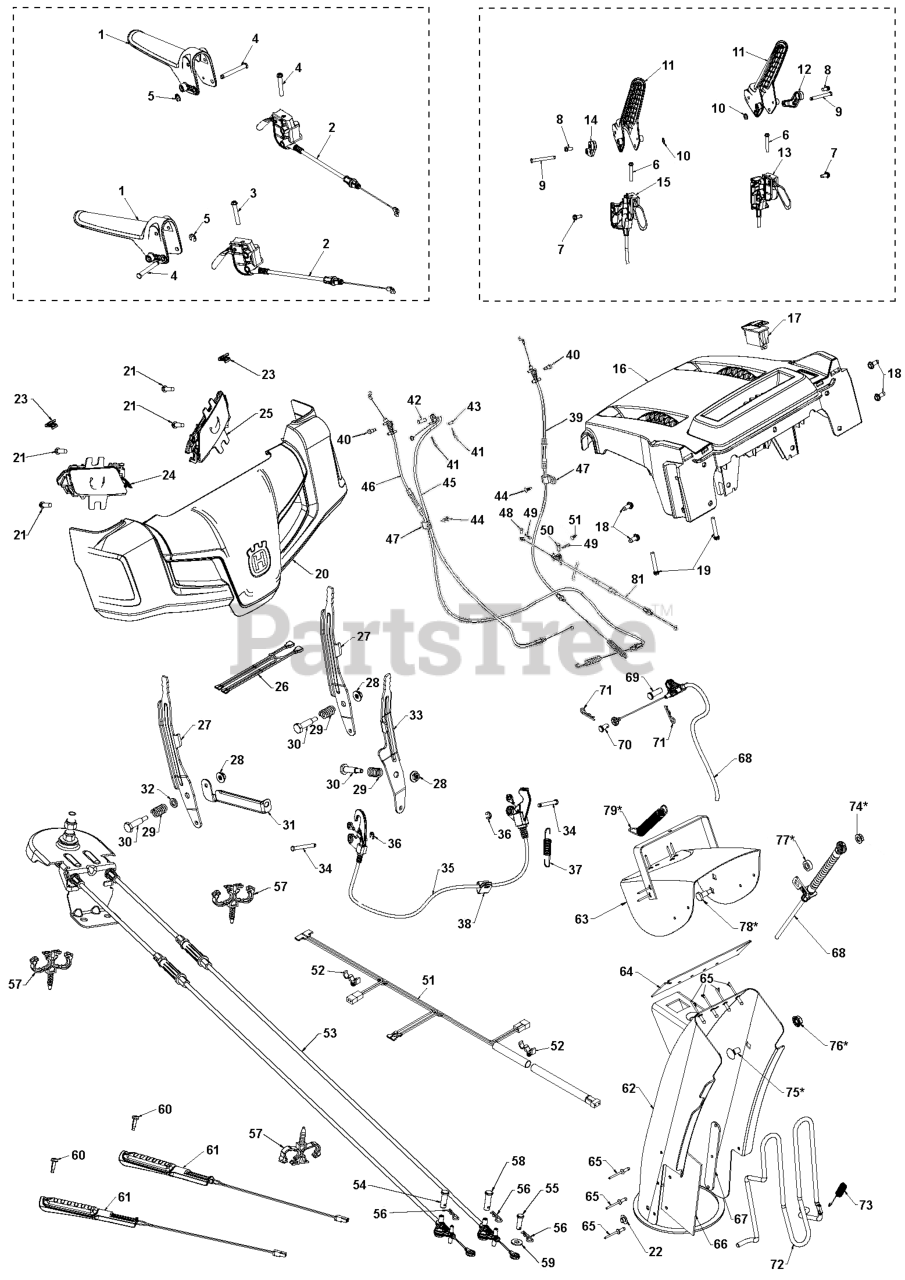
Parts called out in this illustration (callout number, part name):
1	LEVER CONTROL DSST OPP MPP
2	CABLE.CONTROL.PS.OPP.SNOW
3	SCREW HEX WASH MACH BLK 10-24
4	PIN.GROOVED
5	E-RING
6	SCREW HEX_WASH_13-16 X 1.50_H
7	SCREW 14-20 X 5/8
8	SCREW.HWH.13-16X.50
9	PIN.GROOVED
10	E-RING
11	LEVER CONTROL DSST OPP MPP
12	LEVER.CABLE.ARM.RHS.BLACK
13	CABLE.POWER STEERING.RHS
14	LEVER.CABLE.ARM.LHS.BLACK
15	CABLE.POWER STEERING.LHS
16	CONSOLE BASE MULTI CONTROL
17	SWITCH HEATED GRIP BLK
18	SCREW 14-20 X 5/8
19	SCREW HEX_WASH_13-16 X 1.50_H
20	COVER CONSOLE_ASM_HUSQVARNA
21	SCREW.HWH.13-16-5.8.BZP
22	NUT
23	CLIP PANEL ERGO 30603
24	LIGHT ASM.HUSQVARNA.RH
25	LIGHT ASM.HUSQVARNA.LH
26	HARNESS.WIRE.LIGHT.JUMPER
27	LEVER.CONTROL.SPEED/DEFLEC.BLK
28	NUT HEX_LRG FLG_1_4-20_LOCK
29	SPRING.COMPRESSION.82LBS
30	BOLT SHOULDER_HEX HD_1/4-20_3/
31	BRACE.SUPPORT.SPEED.BLACK
32	WASHER.FLAT.625 X .375 NYLON
33	LEVER.CONTROL.CHUTE.ROTATON.BL
34	PIN.GROOVED
35	CABLE INTERLOCK CONTROL ACETAL
37	SPRING RETURN_INTERLOCK_DSST
38	CLIP.CABLE.BLK
39	RP.CABLE.CONTROL.DRIVE
39	CABLE.CONTROL.DRIVE.DSST.OPP
39	CABLE.DRIVE CONTROL W/ADJ
40	CLIP.CABLE.BLK
40	BOLT SHOULDER_1/4-20_TRILOB
41	HAIRPIN.SOFT.ZINC.059X1.125
41	PIN CLEVIS .25 X .31
42	HAIRPIN.SOFT.ZINC.059X1.125
42	PIN CLEVIS 5/16X.875
43	PIN CLEVIS .25 X .31
44	FASTENER.PUSH.O.250X0.783
44	PIN CLEVIS 5/16X.875
45	CABLE.CONTROL.SPEED.DSST.OPP
45	Cables
46	CABLE.CONTROL.AUGER.DSST.OPP.M
46	CABLE.CONTROL.AUGER
47	CLIP.CABLE.BLK
47	FASTENER.PUSH.O.250X0.783
48	PIN CLEVIS .25 X .31
49	HAIRPIN.SOFT.ZINC.059X1.125
50	PIN CLEVIS 5/16X.875
51	RP HARNESS.WIRE.LIGHT & GRIP
51	HARNESS WIRE.LIGHT AND GRIPS
52	PUSH CLIP
53	CABLE ASSY CONTROL
54	PIN CLEVIS 5/16X.875
55	PIN.CLEVIS
56	HAIRPIN.SOFT.ZINC.059X1.125
57	CLIP.CONDUIT.DOUBLE LOOP
58	PIN CLEVIS 5/16 X 1.0 L
58	PIN CLEVIS CLEVIS
59	WASHER FLAT_.250 X .625 X .06
60	GRIP.HANDLE.HEATED
61	SCREW.PAN.HD.TORX.1/4-20X.750
62	CHUTE.WELDMENT.SNOW.ORANGE
62	ASM.CHUTE/DEFLECTOR.668
63	DEFLECTOR.WELDMENT.PNT.ORANGE
64	SEAL.DEFLECTOR
65	RIVET BLIND
66	SHIELD.SNOW.CHUTE
67	STRAP.SHEILD.RETAINER
68	CABLE CONTROL.CHUTE.DEFLECTOR.
68	CABLE.CONTROL.CHUTE.DEFLEC
68	CABLE CONTROL.CHUTE.DEFL.BOWDE
69	PIN CLEVIS 5/16X.875
70	PIN CLEVIS .25 X .31
71	HAIRPIN.SOFT.ZINC.059X1.125
72	GUARD ROD CHUTE GUARD SHORT CL
72	ROD.GUARD.CHUTE (2 2)
73	SPRING.CHUTE.GUARD
81	RB CABLE.CNTRL.SPEED.DSST.OPP
